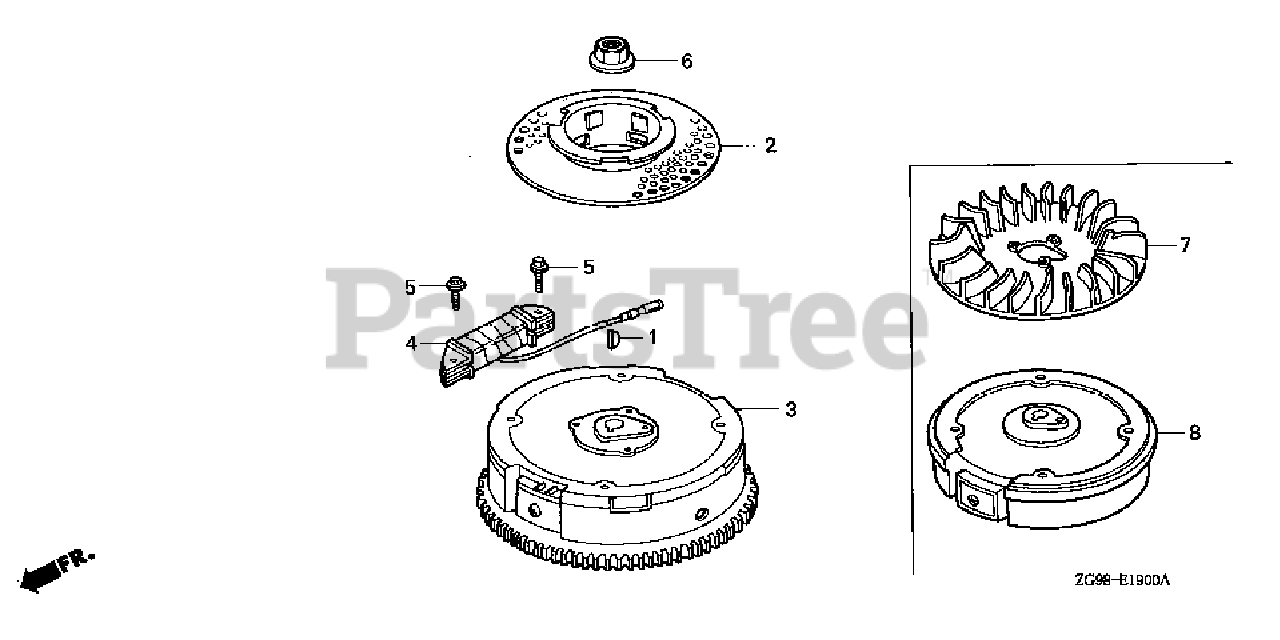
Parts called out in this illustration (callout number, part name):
1	KEY, SPECIAL WOODRUFF (25X18)
5	BOLT, FLANGE (6X14)
6	NUT, SPECIAL (14MM)
7	FAN, COOLING (USA)
8	FLYWHEEL
